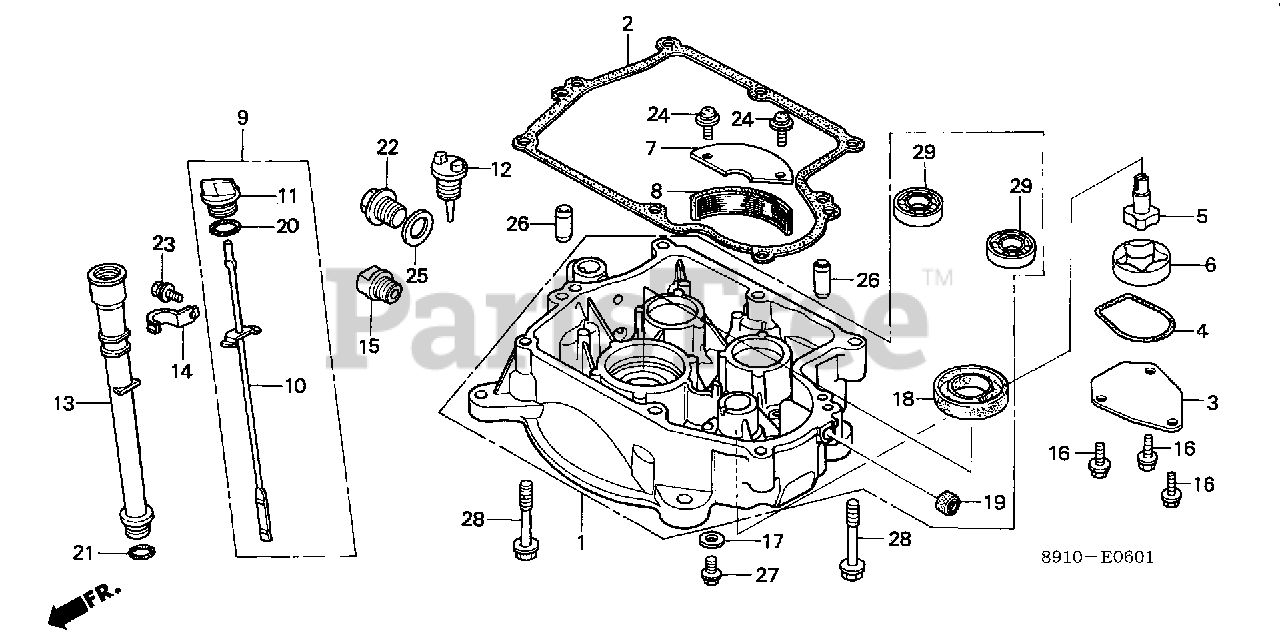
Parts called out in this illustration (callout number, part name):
1	PAN ASSY., OIL
2	GASKET, OIL PAN
3	COVER, OIL PUMP
4	O-RING (42X2.9)
5	ROTOR (INNER)
6	ROTOR, OIL PUMP (OUTER)
7	PLATE, OIL FILTER
8	SCREEN, OIL FILTER
9	GAUGE ASSY., OIL LEVEL
10	GAUGE, OIL LEVEL
11	CAP, OIL (YELLOW)
13	EXTENSION, OIL FILLER
14	CLAMP, EXTENSION
15	ADAPTER, OIL DRAIN EXTENSION
16	BOLT, FLANGE (6X12) (CT200)
17	WASHER A (8MM)
18	OIL SEAL (30X46X8)
19	OIL SEAL (6X11X4) (ARAI)
20	O-RING (26X2.7)
21	O-RING (16.8X2.4)
22	BOLT, DRAIN PLUG (20MM)
23	BOLT-WASHER (6X10)
24	SCREW-WASHER (5X12)
25	WASHER, DRAIN PLUG (20MM)
26	PIN, DOWEL (8X14)
27	BOLT, FLANGE (8X16)
28	BOLT, FLANGE (8X45)
29	BEARING, RADIAL BALL (6203)
